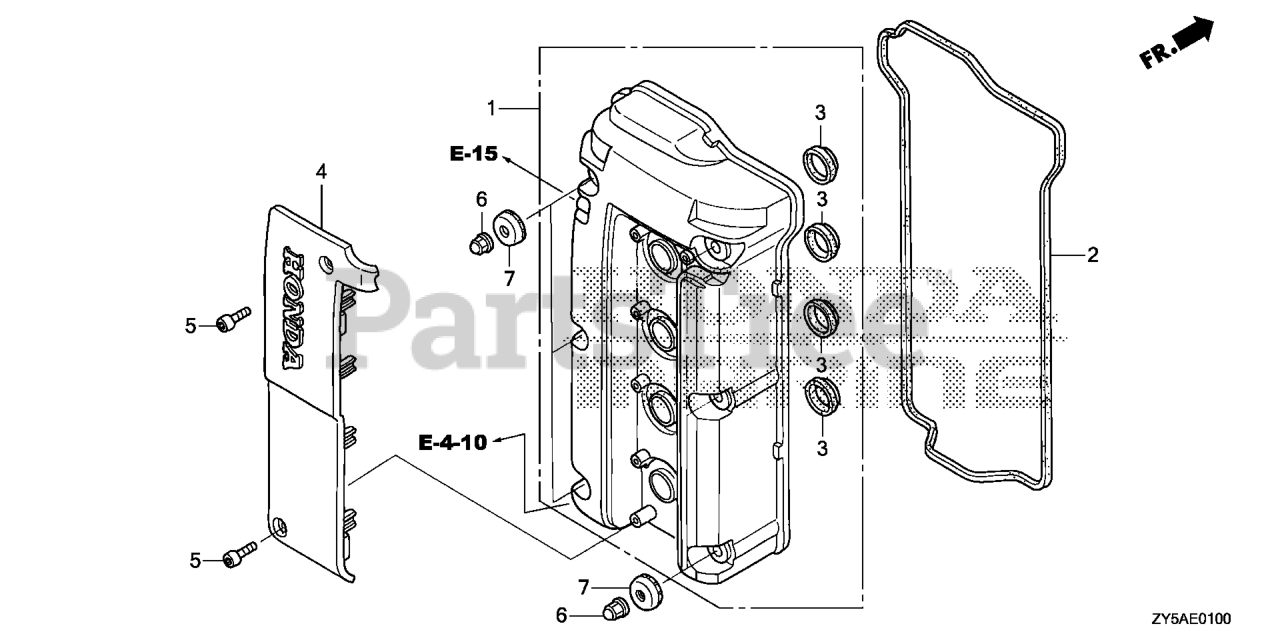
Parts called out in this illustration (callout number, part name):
1	COVER, CYLINDER HEAD *NH8* (DARK GRAY) (FOR 14540-RWC-A02)
2	GASKET, CYLINDER HEAD COVER
3	SEAL, SPARK PLUG TUBE (NOK)
4	COVER, PLUG HOLE COIL
5	BOLT, SOCKET (6X25)
6	NUT, FLANGE CAP (6MM)
7	WASHER, HEAD COVER
